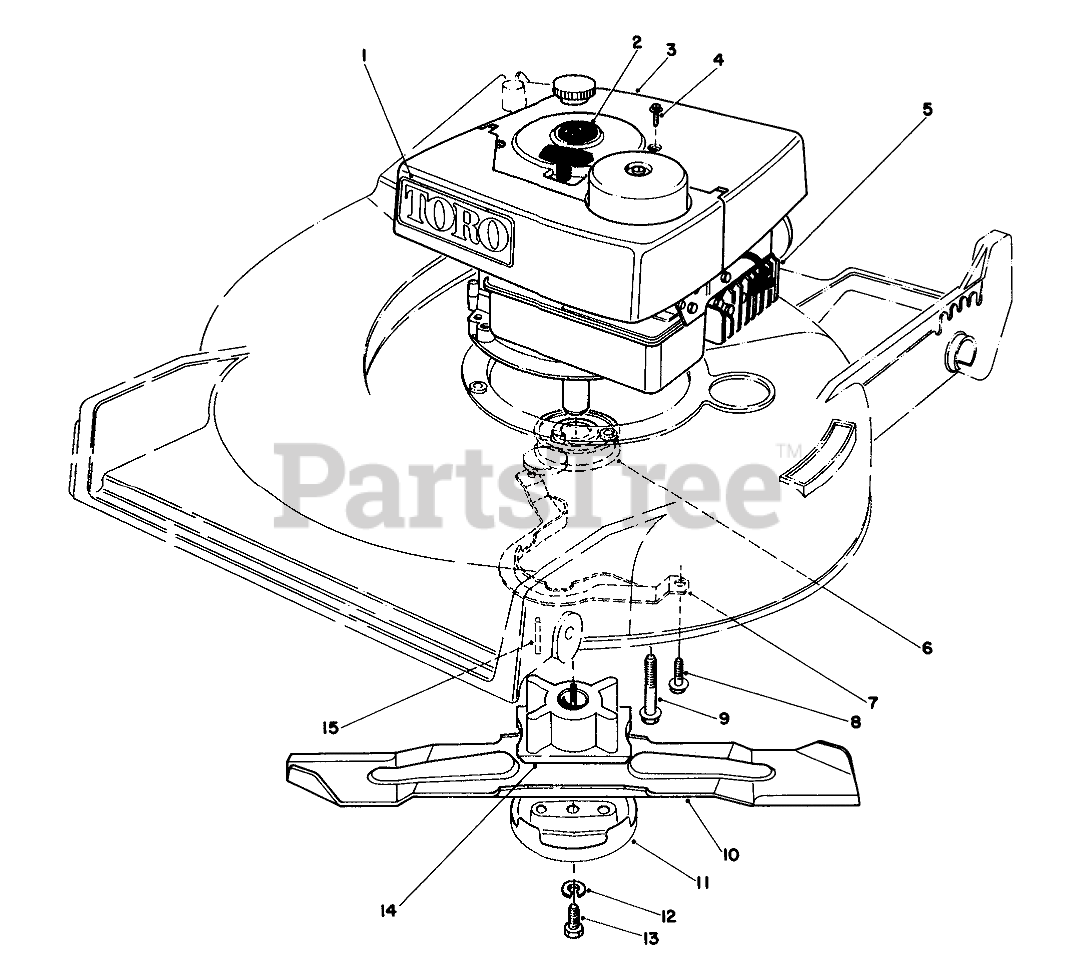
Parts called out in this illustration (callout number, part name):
1	Decal Tow
2	Decal-Shroud
3	ENGINE SHROUD ASM
4	TAPPING SCREW
6	Pulley
7	BELT GUIDE
8	Screw
9	3/8-16 X 2 CAPSCREW
10	BLADE-21in
11	Anti Scalp Cup
12	WASHER-LOCK
13	SCREW-BLADE
14	BLADE RETAINER(DEEP)
15	KEY-SQUARE
